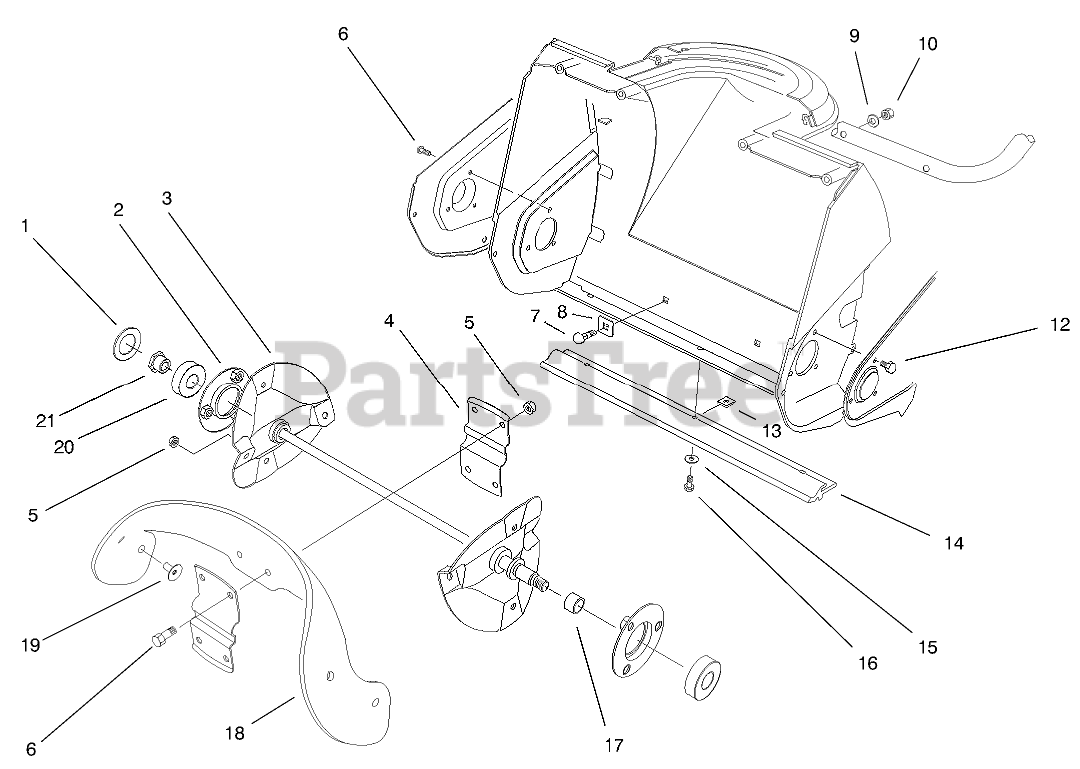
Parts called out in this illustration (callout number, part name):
1	WASHER-RUBBER
2	FLANGE BEARING ASM
3	ROTOR SHAFT ASM
4	SUPPORT-ROTOR
5	NUT-LOCK, NI
6	SCREW-HHF
7	SCREW-CARR
8	WASHER-SQUARE
9	WASHER
10	NUT-LOCK, NI
12	SCREW-HH
13	NUT-CLIP, U
14	SCRAPER
15	WASHER-FLAT
16	SCREW-HWHTF
17	SPACER
18	BLADE-ROTOR
19	SCREW
20	BEARING-BALL
